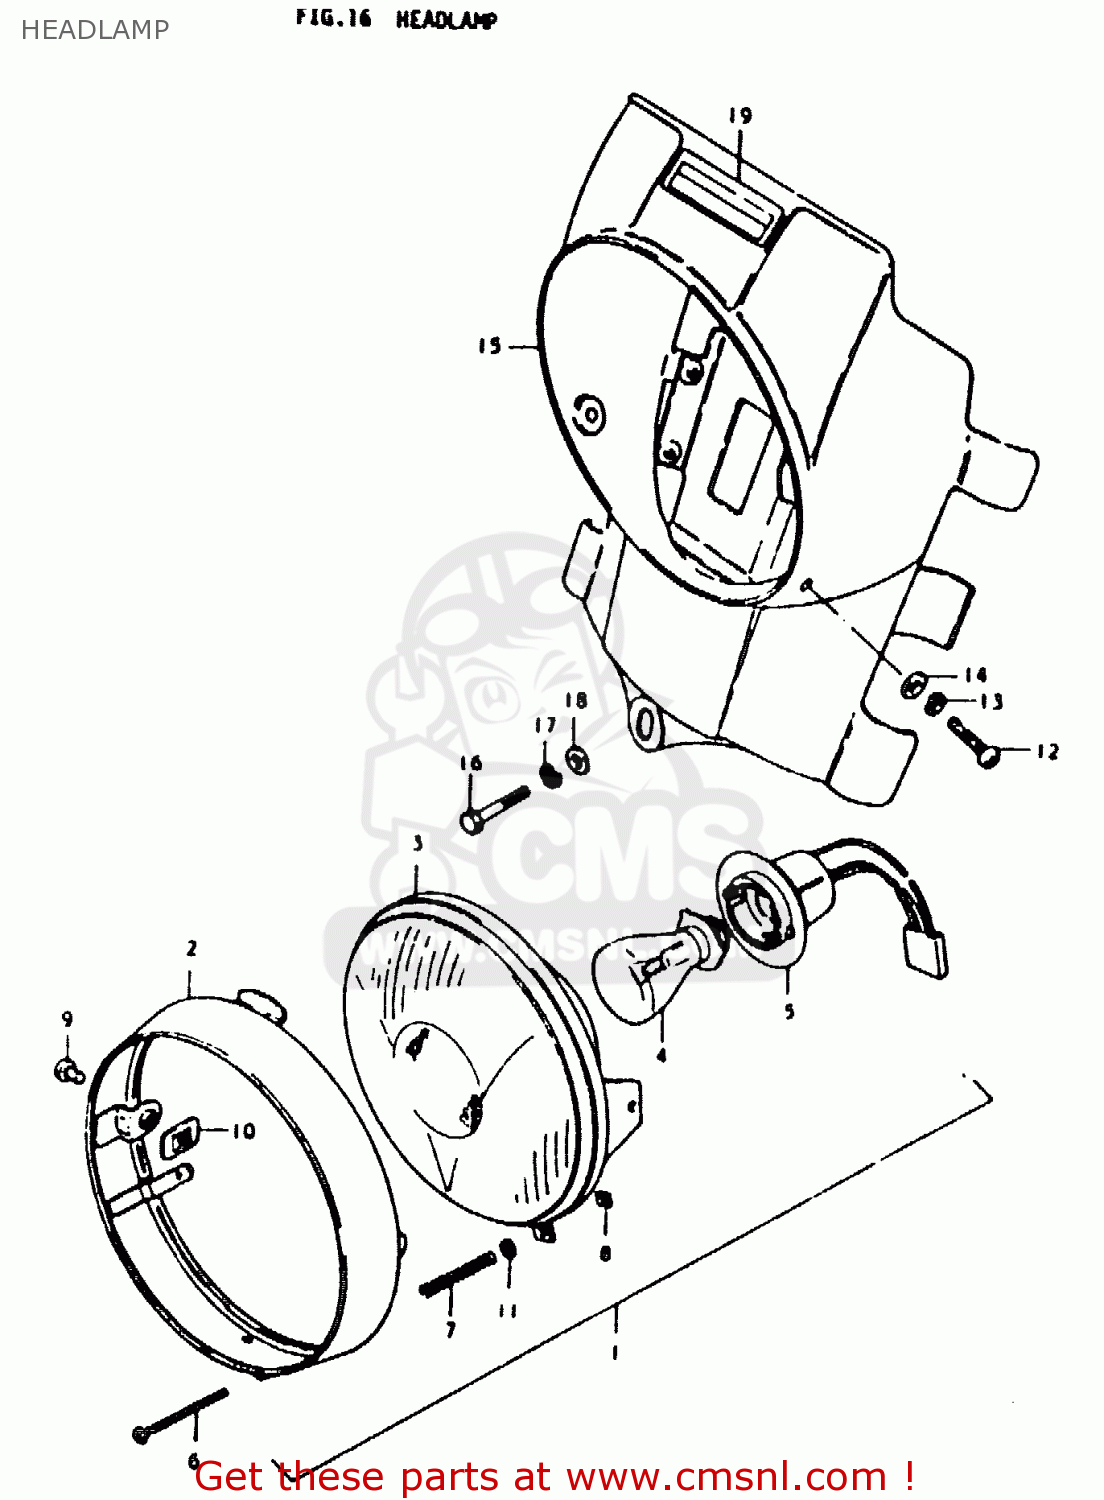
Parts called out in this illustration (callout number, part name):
1	HEADLAMP ASSY
2	RIM
3	LAMP UNIT
4	BULB(6V25/25W,STANLEY,A7007)
5	SOCKET,HEADLAMP
6	SCREW,HEADLAMP ADJUST
7	SPRING
8	NUT,HEADLAMP ADJUSTER
9	SCREW
10	NUT
11	WASHER
12	SCREW
13	LOCK WASHER
14	WASHER
15	HOUSING, HEADLAMP
16	BOLT
17	LOCK WASHER
18	WASHER
19	TAPE, HOUSING
